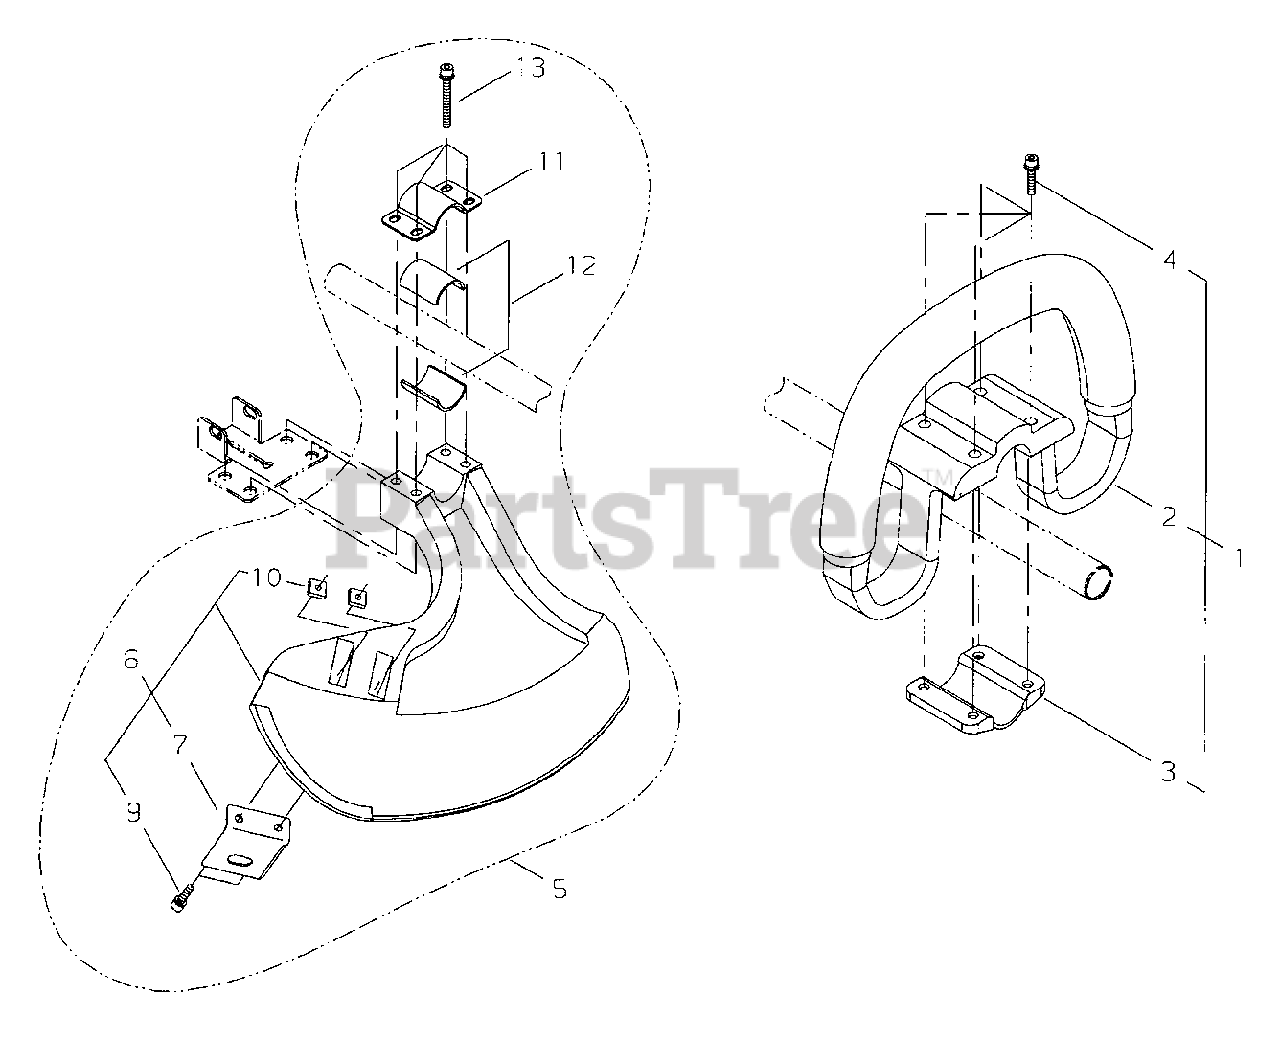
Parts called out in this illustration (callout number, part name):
1	HANDLE ASSY
2	HANDLE
3	CLAMP - LOWER
4	SCREW - 5X25
5	DEBRIS SHIELD KIT
6	DEBRIS SHIELD ASSY
7	KNIFE, TRIMMER LINE
8	SCREW - 5X16
9	NUT - 5
10	CLAMP - UPPER
11	SPACER
12	SCREW - 5X45
